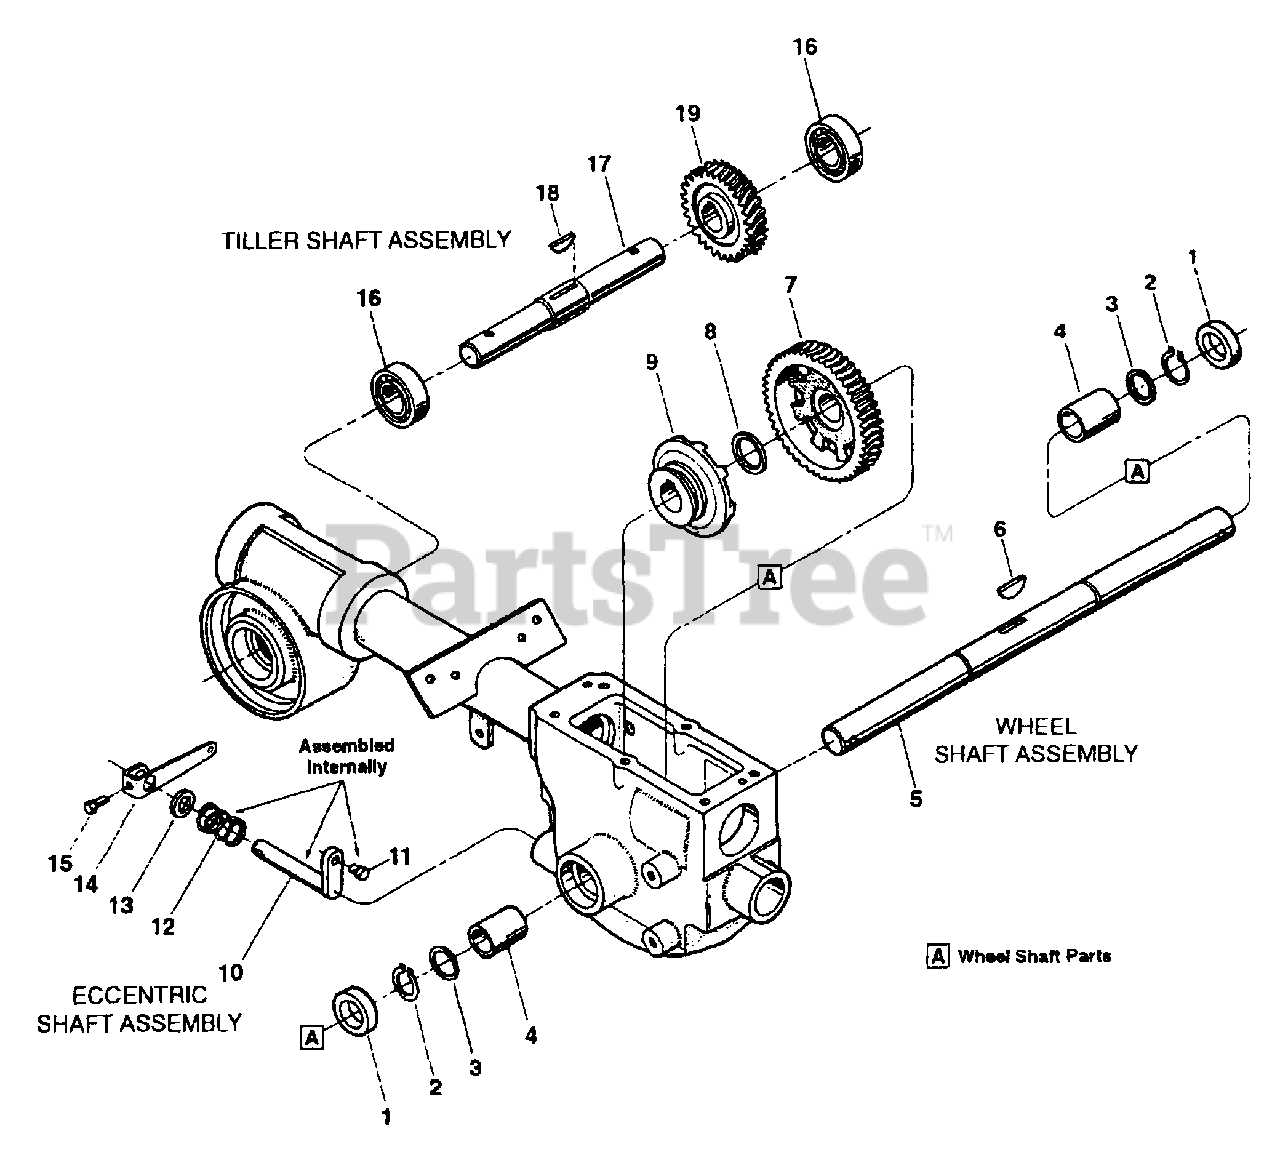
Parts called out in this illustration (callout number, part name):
1	Oil Seal-left and right sides
2	Ring-retaining, heavy-duty, external
3	Shim-1-1/64 I.D, .062 thick
4	Bushing
5	Wheel Shaft (axle)
6	Key-hi-pro (1/4 x 1-5/16), clutch to wheel shaft
7	Gear-wheel drive (worm gear), cast iron
8	Shim-between key and gear (1.016 I.D. x 1.468 O.D. x .062 thick)
9	Clutch-wheel drive, cast iron
10	Eccentric Shaft-wheel clutch shifting
11	Pin-eccentric shaft
12	Spring
13	Oil Seal-eccentric shaft
14	Lever-eccentric shaft
15	Screw-hex hd., 1/4-20 x 1/2
16	Ball Bearing-for tiller shaft
17	Tiller Shaft
18	Key-woodruff, 1/4 x 1-1/4
19	Worm Gear-bronze, tiller drive
